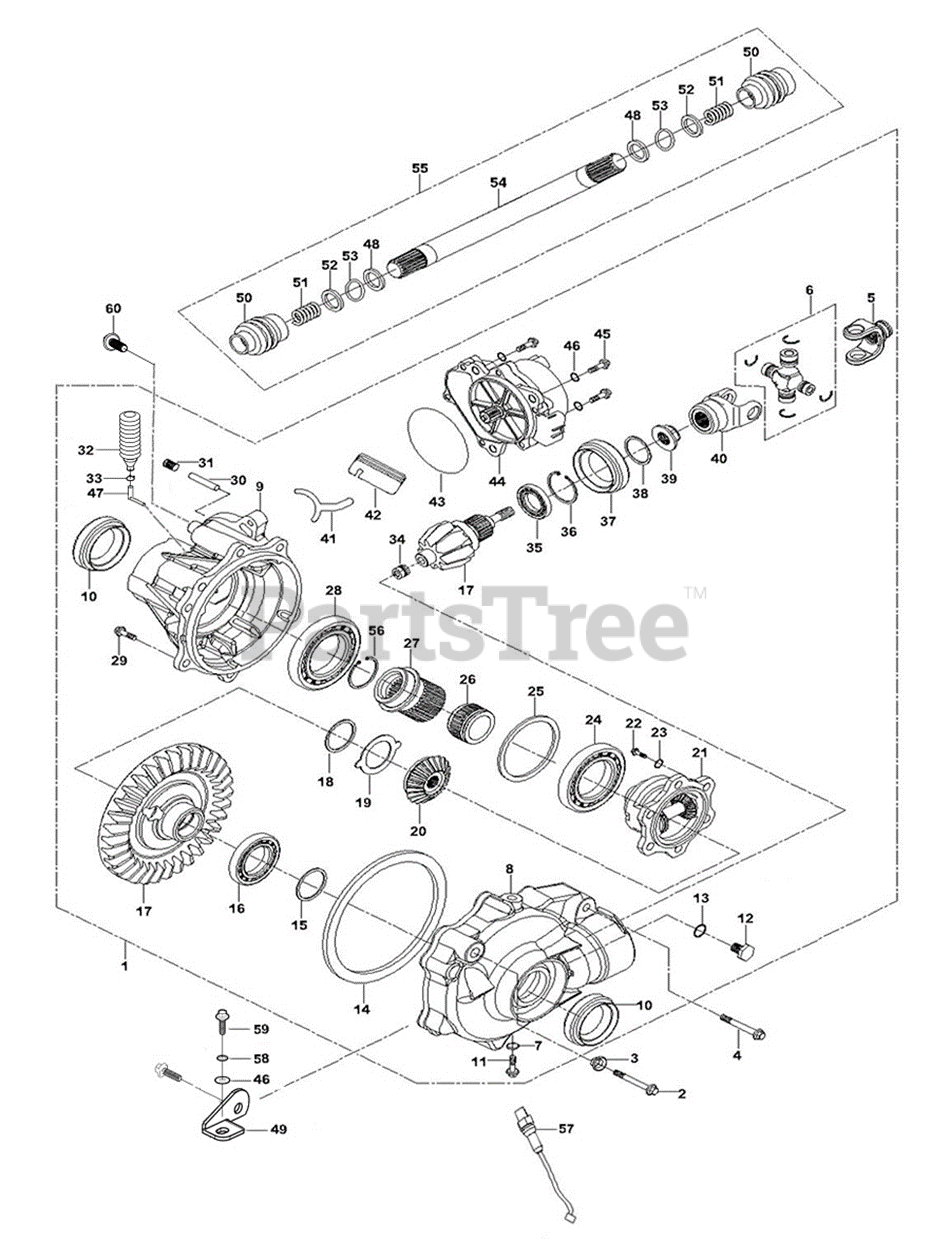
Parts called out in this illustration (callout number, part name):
1	FRONT DIFFERENTIAL
2	HEX HEAD BOLT M10X1.25-145
3	LOCK NUT M10X1.25
4	HEXAGON FLANGE BOLT M10X30
5	U-JOINT YOKE (SPLINED)
7	O-RING 1.5X9
8	GEARCASE - LEFT
9	FRONT DIFFERENTIAL COVER
10	SEAL 24X38X8
11	FLANGE BOLT M10X1.25X16
12	DRAIN PLUG M14X1.5-10
13	O-RING 12.5X1.5
14	O-RING 140X2.65
15	ADJUSTING WASHER 50X 61.5X0.1
16	BALL BEARING (6007)
18	ADJUSTING WASHER 40X57X0.1
19	LOCK WASHER
21	DIFFERENTIAL CASE
22	HEXAGON BOLT M10X1.25X16
24	BEARING 61912
25	ADJUSTING WASHER 71X83X0.1
26	SHAFT SLEEVE
28	BEARING 16007
29	FLANGE BOLT M8X25
30	ROLLER PIN 5X75
31	BOLT STOPPER M8X10
33	CIRCLE CLIP
34	NEEDLE BEARING HK1512
35	BALL BEARING (6007)
37	SEAL 48X65X9
38	O-RING 14X7
39	LOCK NUT M14X1.5
40	U-JOINT YOKE (FRONT)
41	FORK SHAFT
43	O-RING 81X2
44	GEAR MOTOR
45	HEXAGON SOCKET CAPSCREW M8X20
47	FRONT DIFFERENTIAL FITTING
48	NARROW BAND CLAMP
49	FRONT AXLE MOUNTING PLATE
50	REAR AXLE RUBBER BOOT
51	REAR AXLE SPRING
54	FRONT DRIVE SHAFT
55	FRONT DRIVE SHAFT ASSEMBLY
57	SPEED SENSOR
58	SPRING WASHER-8
59	HEXAGON FLANGE BOLT M8X20
60	HEX FLANGE BOLT M10X1.25X20
